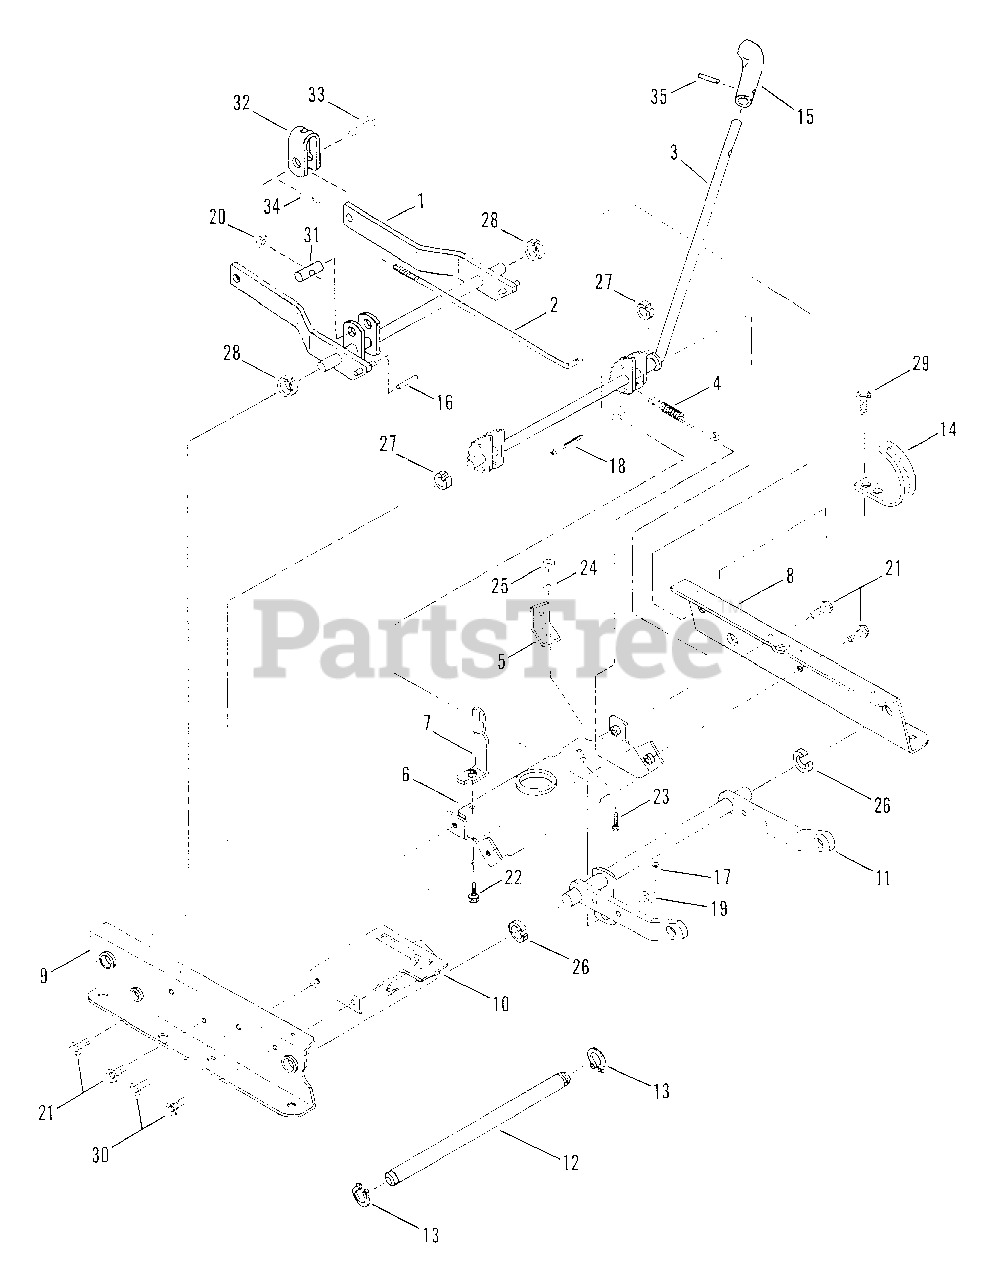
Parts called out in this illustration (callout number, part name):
1	ASSEMBLY, Rear Lift Arm (25,26,28,30 & 33" Models)
2	ROD, Leveling (15.3" L, 3/4-24 thread)
3	CAM LIFT LEVER
4	SPRING, Cam Lift
5	ANCHOR (Auto. Blade Control Models)
6	BRACE, Top
7	GUIDE, Belt
8	RAIL, Left Hand
9	RAIL, Right Hand
10	ASSEMBLY, Clutch-Plate
11	FRONT LIFT ARM, Non-Adjustable, (25,26,28 & 30" Models)
12	SUPPORT ROD (Front Lift Arm to Front End)
13	RING, 5/8" External Retaining
14	PLATE, Indicator
15	GRIP, Height Adjustment Lever
16	PIN, Roll
17	PIN, 1/8x3/4" Cotter
18	PIN, 5/32x1" Cotter
19	WASHER, 3/8" Flat
20	NUT, 3/8-24 Hex
21	SCREW, 3/8-16x1/2" Hex Hd.,Self-Tapping
22	SCREW, 5/16-18x5/8" Hex Self-Tapping
23	SCREW, 5/16-24x3/4" Hex Head Cap
24	LOCKWASHER, 5/16 Internal Tooth Lock
25	NUT, 5/16-24 Hex
26	RING, Red
27	RING, White
28	RING, Blue
29	SCREW, 3/8-16x3/4" Hex Flange Lock
30	SCREW, 5/16-18x1/2" Self-Tapping
31	PIVOT, Leveling
32	CLEVIS
33	PIN, 3/8 x 1 1/16" Clevis
34	PIN, 3/32x3/4" Cotter
35	ROLL-PIN
